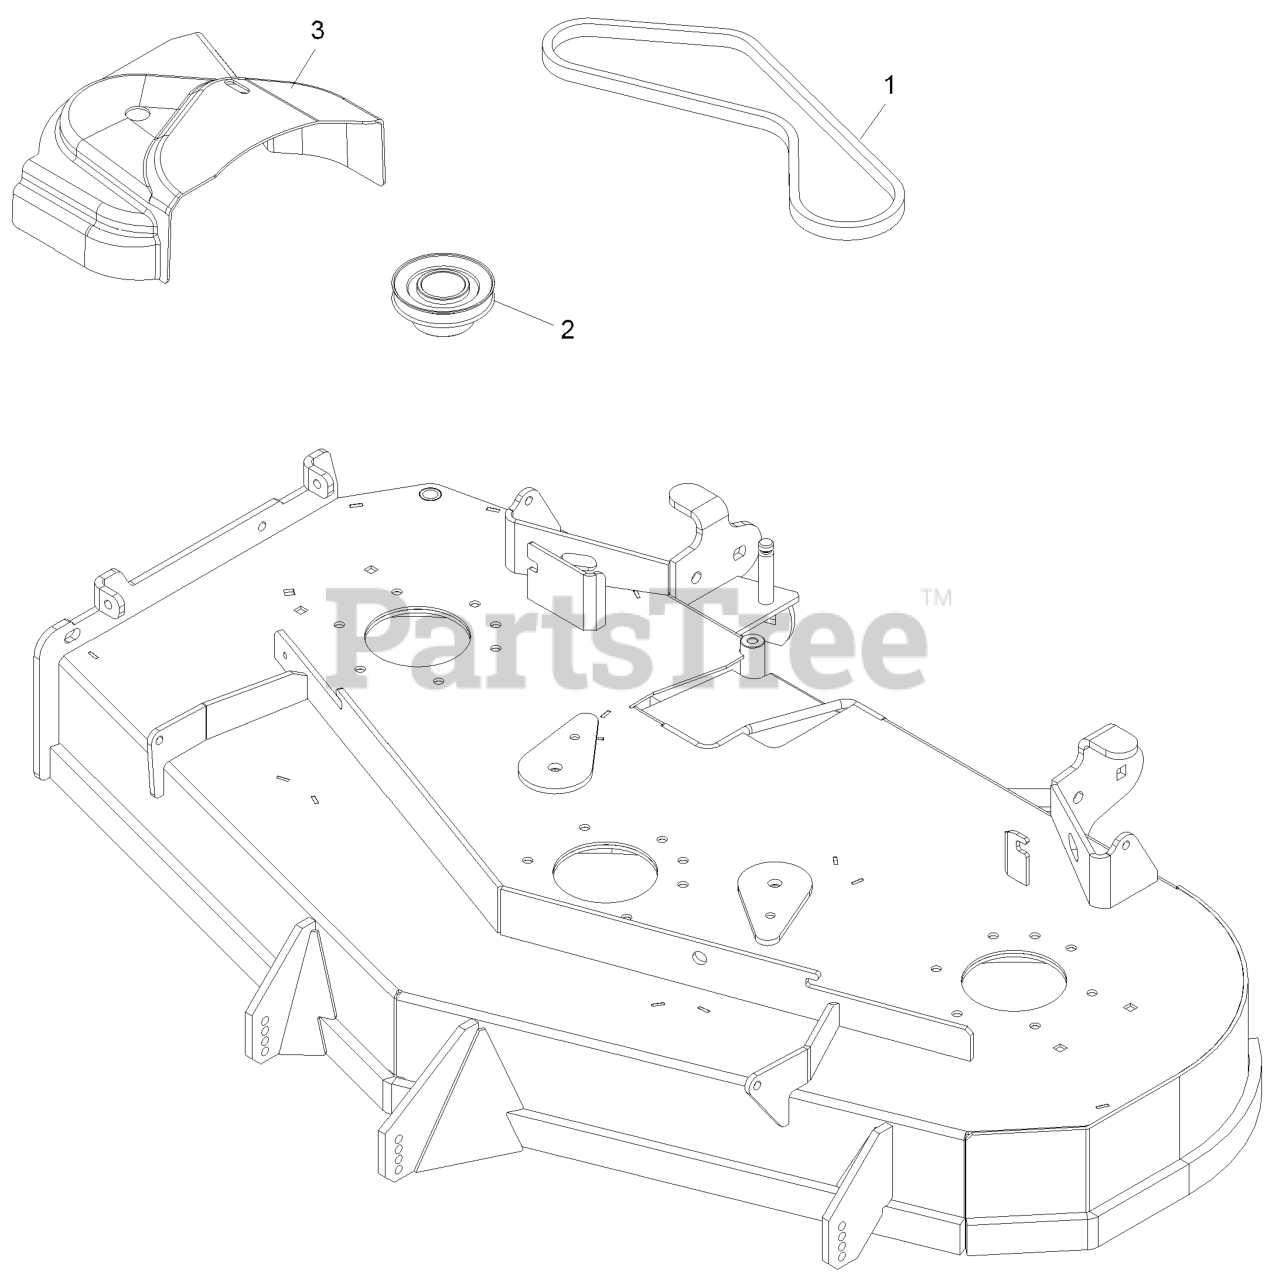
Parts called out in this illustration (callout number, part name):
1	Belt, Blower Drive 52
2	Sheave,Drive Lzuv 526
3	Cover,Belt Uv 52
